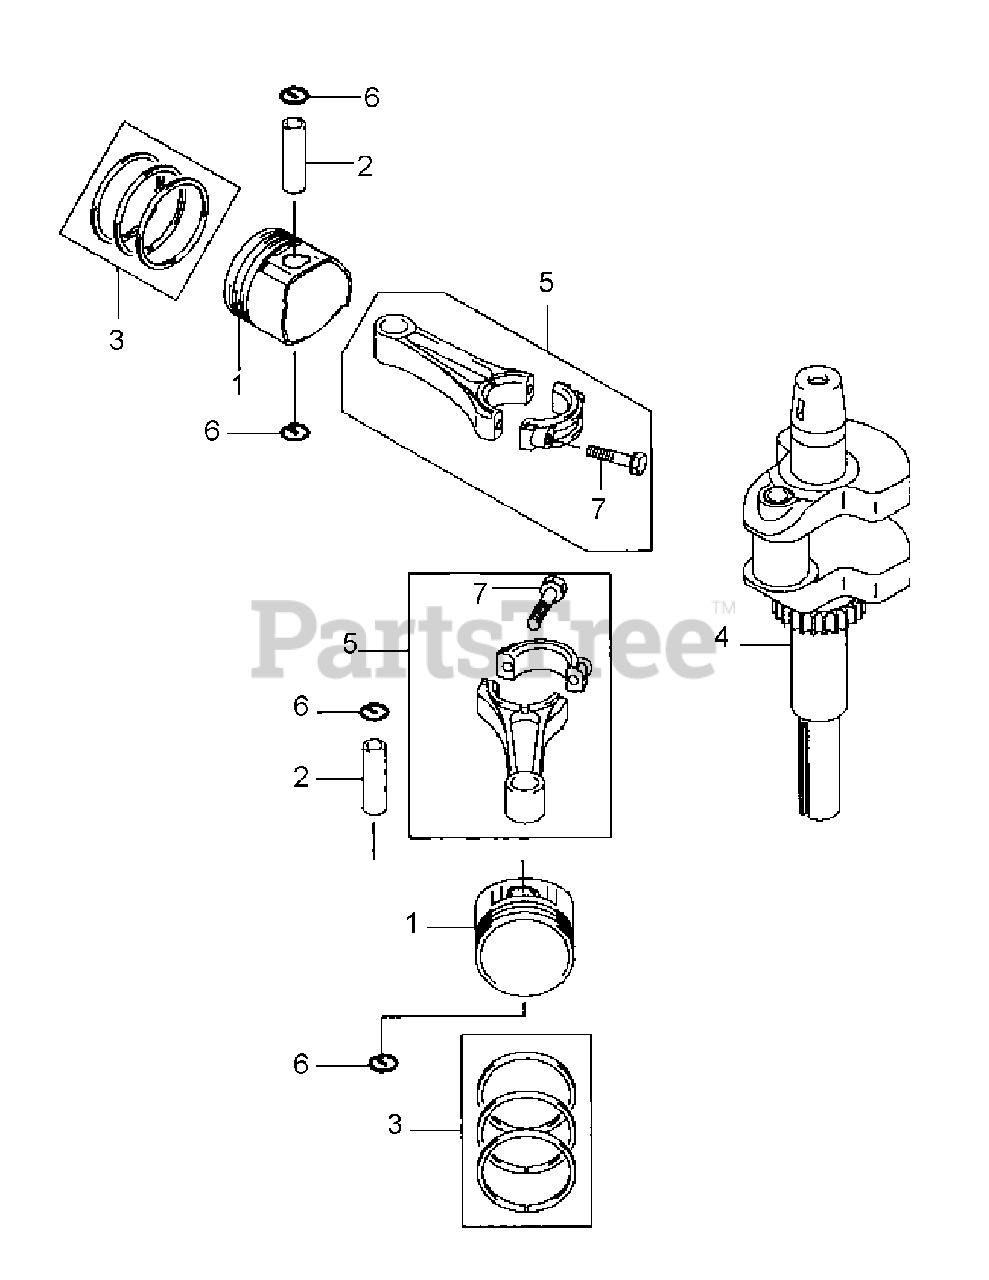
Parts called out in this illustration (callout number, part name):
1	PISTON-ENGINE
3	RING-SET-PISTON
4	CRANKSHAFT-COMP
5	ROD-ASSY-CONNECTING
7	BOLT, 6x35
